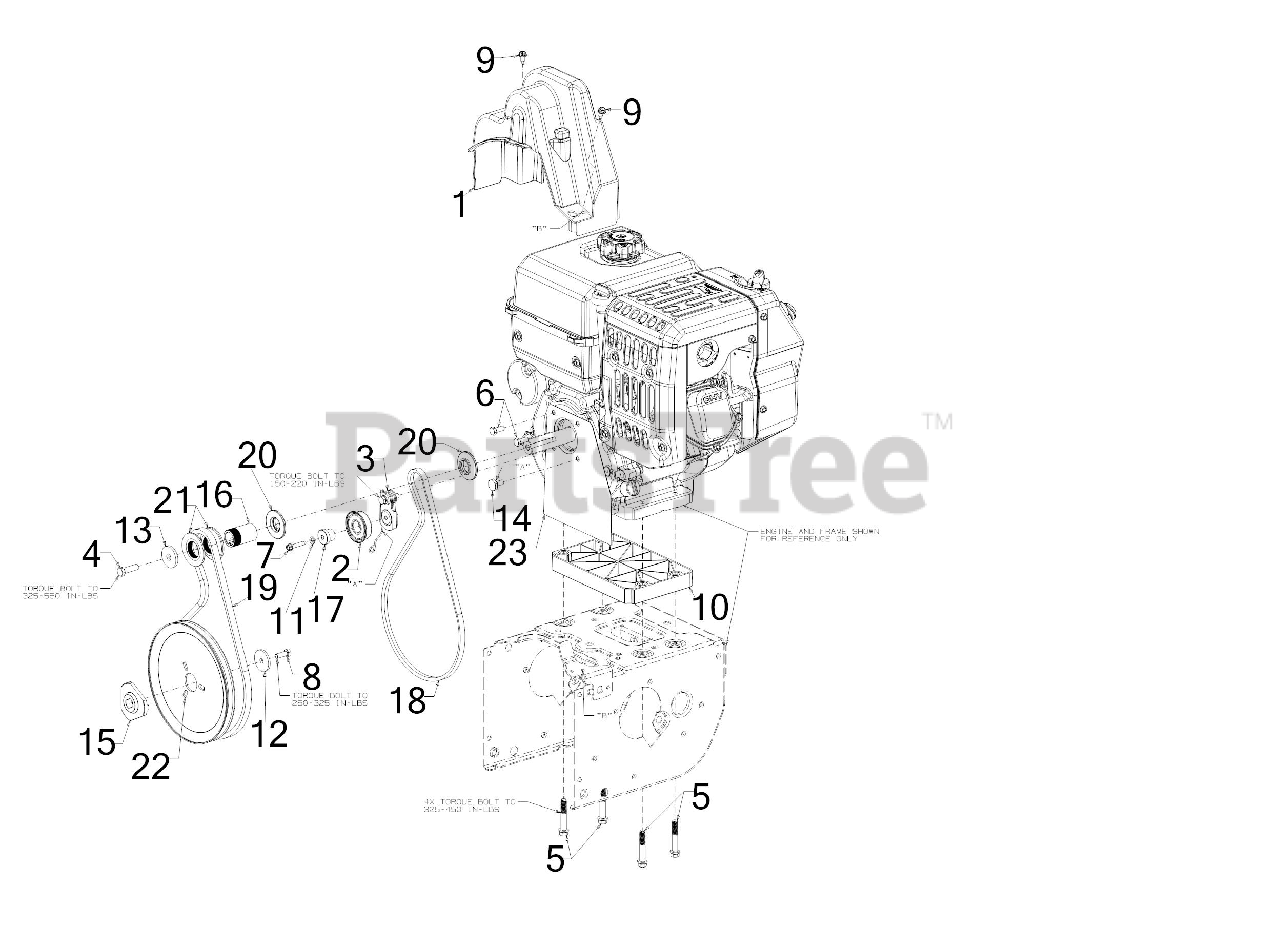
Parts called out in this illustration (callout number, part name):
1	BELT COVER ASSEMBLY
2	IDLER PULLEY ASSEMBLY
3	IDLER ASSEMBLY
4	SCREW 3/8-24X1.25
5	SCREW 3/8-16 x 2.25
6	SCREW 5/16-24 x .750 GR5
7	SCREW 1/4-20 x 1.25
8	SCREW 5/16-24 x .875 GR5
9	SCREW 1/4-20X.625
10	ENGINE MOUNTING SPACER
11	LOCK WASHER
12	FLAT WASHER
13	FLAT WASHER .45 x 1.5 x .172 HT
14	SHOULDER SCREW
15	ADAPTER PULLEY .75 DIA W/DD
16	PULLEY SPACER
17	SHOULDER SPACER
18	DRIVE BELT 3L X 36.90
19	AUGER BELT .500 X 37.74
20	HALF PULLEY-3/8 V x 1.7160
21	HALF PULLEY 4L-V x 2.40 OD
22	AUGER PULLEY 8.5 OD
23	ENGINE PLATE (FRONT)
